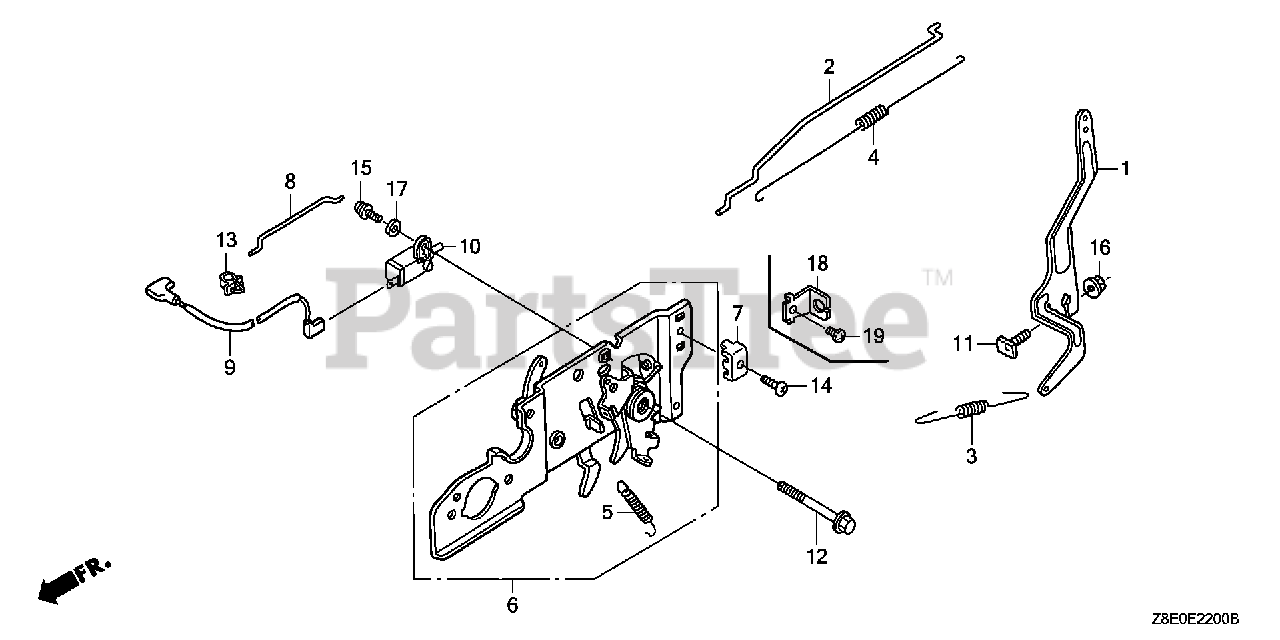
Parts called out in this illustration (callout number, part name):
1	ARM, GOVERNOR
2	ROD, GOVERNOR
3	SPRING, GOVERNOR
4	SPRING, THROTTLE RETURN
5	SPRING, LEVER
6	BASE, CONTROL
7	HOLDER, CABLE
8	ROD, CHOKE
11	BOLT, GOVERNOR ARM
12	BOLT, FLANGE (6X45) (CT200)
14	SCREW, PAN (5X16)
16	NUT, FLANGE (6MM)
